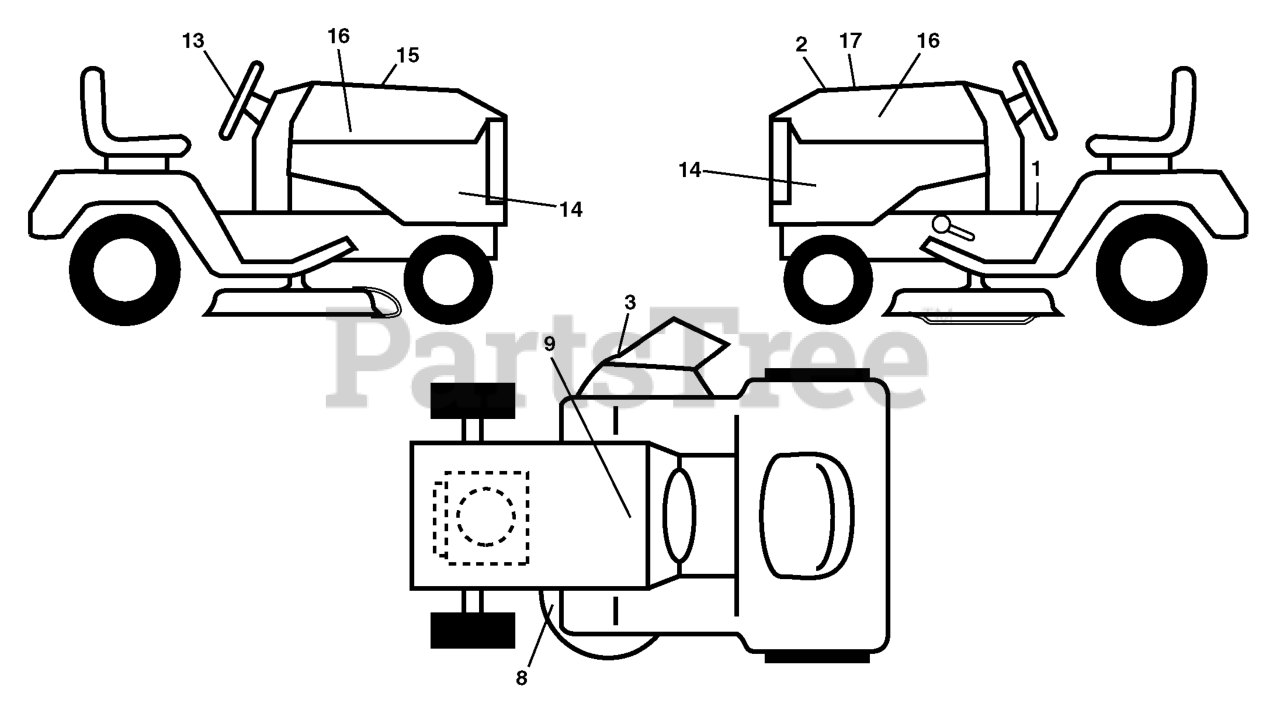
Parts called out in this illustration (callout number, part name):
1	DECAL.FENDER.OPER.TEX.
2	DECAL.HOOD.TOP.INSERT.
3	DECAL.WARN.KEEP.HAND.AWAY
8	DECAL V BELT SCHEMATIC
9	DECAL BTRY SYMBOLS
13	DECAL.STEERING.HUSQ.BLUE
14	DECAL.PANEL.SIDE.YTH20F42T
15	DECAL HOOD CUST. RESP.
16	DECAL.HOOD.NAMELOGO.HUSQ
17	DECAL.PLMNT.KOHL.20HP.
